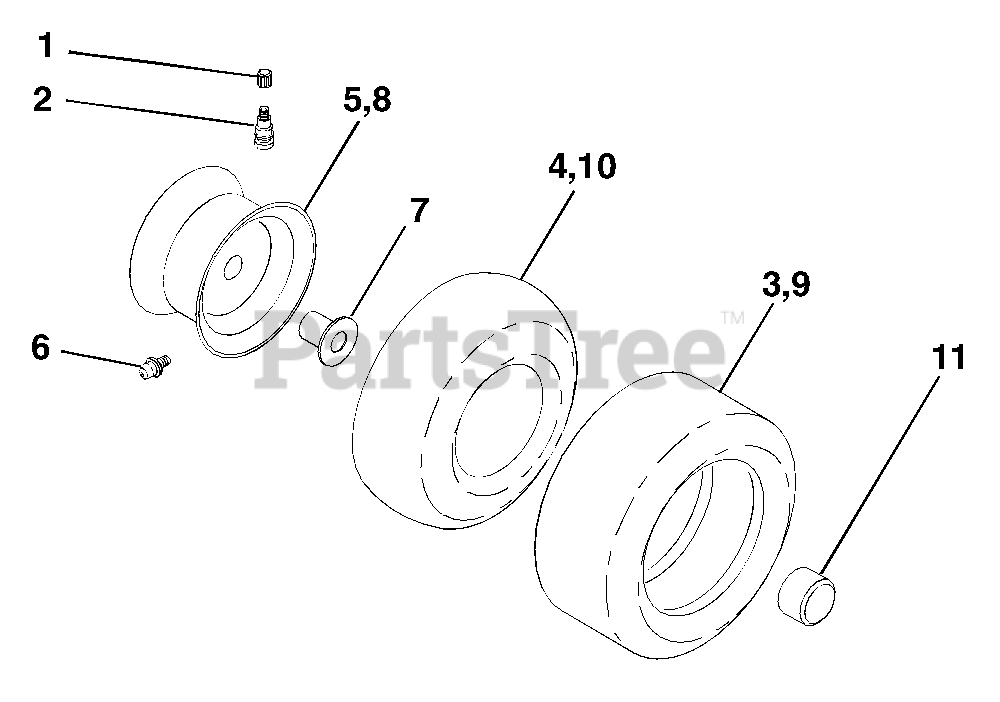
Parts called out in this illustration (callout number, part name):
1	Cap, Tire valve
2	Stem, Valve
3	Tire, Front
4	Tube, Front (Service item only)
5	Rim assembly, 6"front
6	Fitting, Grease (Front wheel only)
7	Bearing, Flange (Front wheel only)
8	Rim assembly, 8" rear
10	Tube, Rear (Service item only)
11	Cap, Hub Axle
